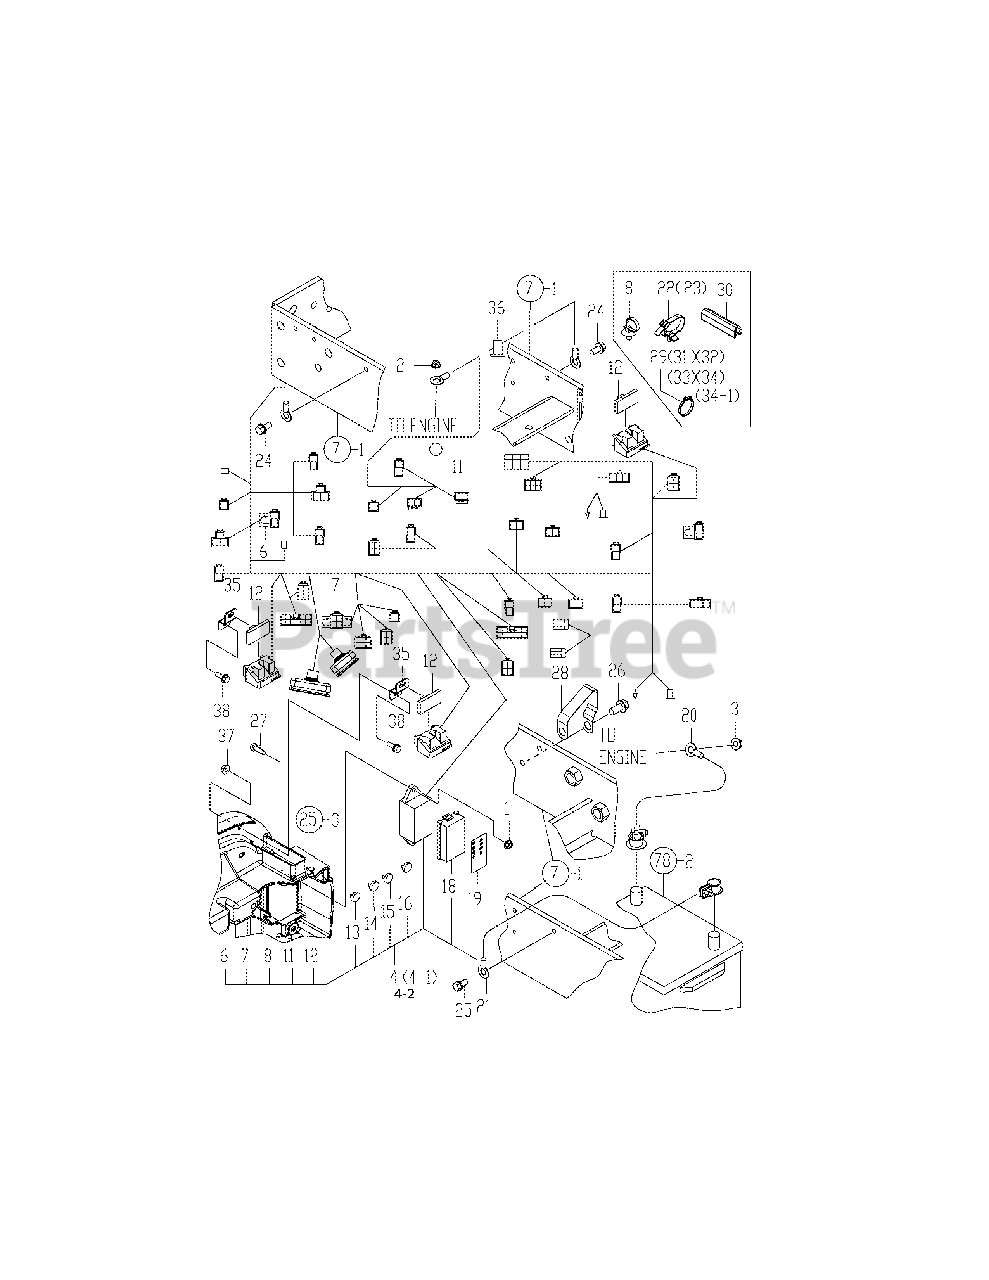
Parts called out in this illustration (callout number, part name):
4	Harness Assy,Wire
4-1	Harness Assy,Wire
4-2	Harness Assy,Wire
11	Blow, Slow Fuse 60A
18	Cover, Fuse Box
20	Cable, Battery +
21	Cable,Battery Neg.
28	Wire, Engine Earth
35	Stay, Relay
36	Sticker, Cable 18
37	Nut, M6
38	Bolt, 6X 16
